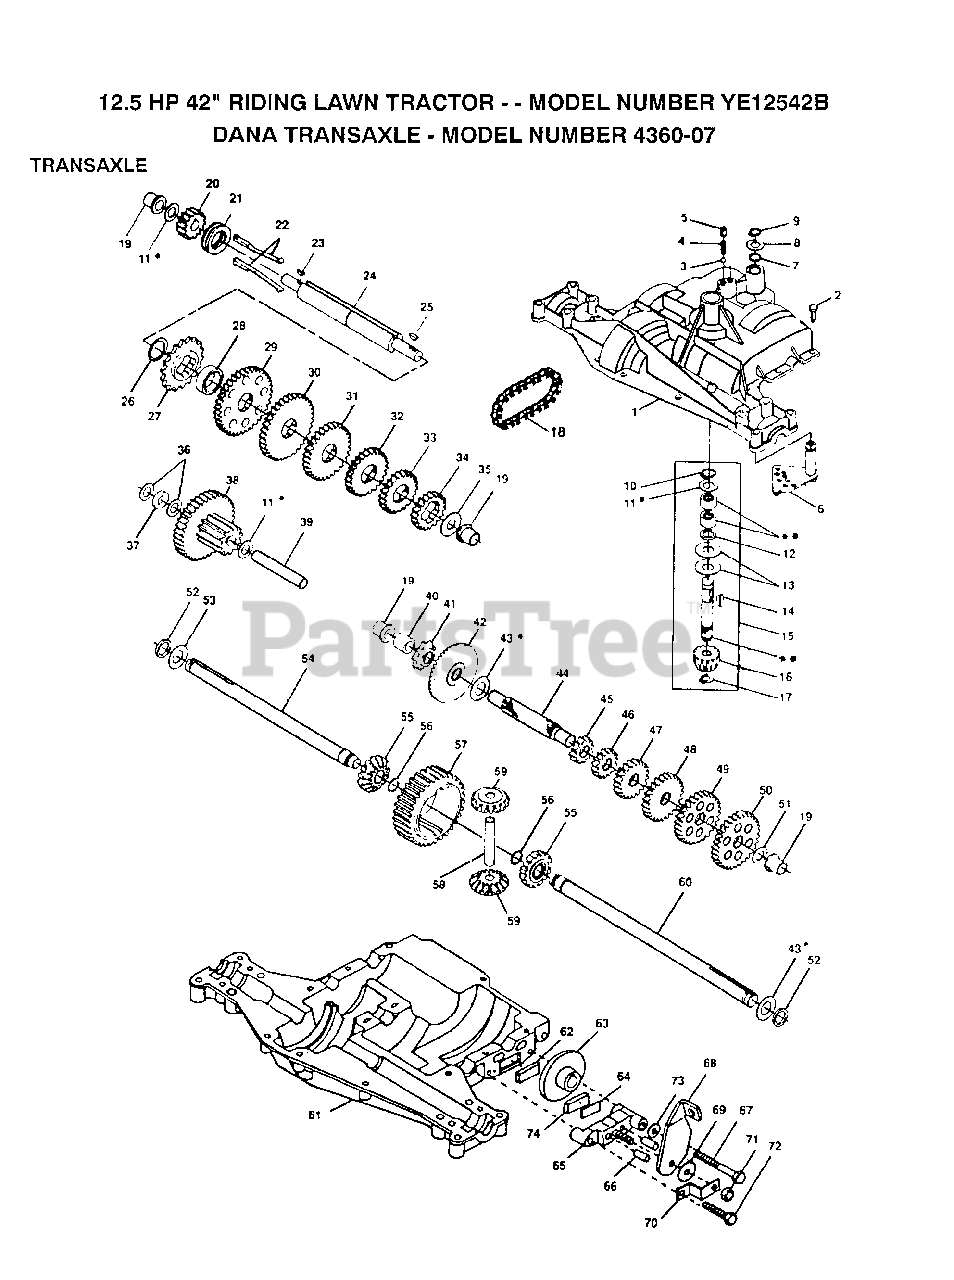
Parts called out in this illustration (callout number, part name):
1	HOUSING UPPER
3	BALL DETENT
4	SPRING, DETENT
5	SCREW, SET
6	ASSY SHIFTER
8	WASHER PLAIN
9	RING RETAINING
10	RING RETAINING
11	WASHER PLAIN
13	WASHER, PLAIN .632 X 1.38 X .046
14	KEY WOODRUFF #9
15	ASSY KIT INPUT SHAFT
16	PINION, BEVEL, 14 TEETH
17	RING, RETAINING
18	CHAIN, 24 PITCHES
19	BEARING, FLANGE
20	GEAR SPUR, 14 TEETH
21	COLLAR CLUTCH
22	KEY CLUTCH
23	KEY WOODRUFF #3
24	SHAFT INTERMEDIATE
25	KEY, WOODRUFF, #61
26	RING, RETAINING
27	SPROCKET, 18 TEETH
29	GEAR, SPUR, 37 TEETH
30	GEAR, SPUR, 35 TEETH
31	GEAR, SPUR, 30 TEETH
32	GEAR, SPUR, 25 TEETH
33	GEAR, SPUR, 22 TEETH
35	WASHER, PLAIN .640 X 1.37 X .061
36	WASHER, PLAIN .632 X 1.00 X .026
37	SPACER .630 X 1.00 X .169
38	ASSY GEAR COMB 12&35 TEETH
39	SHAFT IDLER
40	SPACER .635 X .875 X .755
41	SPROCKET, 9 TEETH
42	GEAR, BEVEL, 42 TEETH
43	WASHER PLAIN
44	SHAFT, DRIVE
45	GEAR, SPUR, 12 TEETH
46	GEAR SPUR, 15 TEETH
47	GEAR, SPUR, 20 TEETH
48	GEAR, SPUR, 25 TEETH
49	GEAR, SPUR, 28 TEETH
50	GEAR, SPUR, 31 TEETH
51	WASHER, PLAIN .632 X 1.00 X .060
53	WASHER PLAIN
54	AXLE LEFT HAND
55	GEAR, MITER, 15 TEETH
56	RING, RETAINING
57	GEAR, SPUR, 32 TEETH
58	SHAFT, CROSS
59	GEAR, MITER, 15 TEETH
60	AXLE RIGHT HAND
61	HOUSING LOWER
62	PUCK, FRICTION
63	DISC, BRAKE
65	JAW, BRAKE
66	PIN, DOWEL
67	SCREW TAPPING
68	LEVER, ACTUATING
69	WASHER, PLAIN .321 X 1.00 X .055
70	BRACKET, ANTI-ROTATION
71	LOCKNUT 5/16-24
72	SCREW TAPPING
73	WASHER PLAIN
74	PUCK, FRICTION
